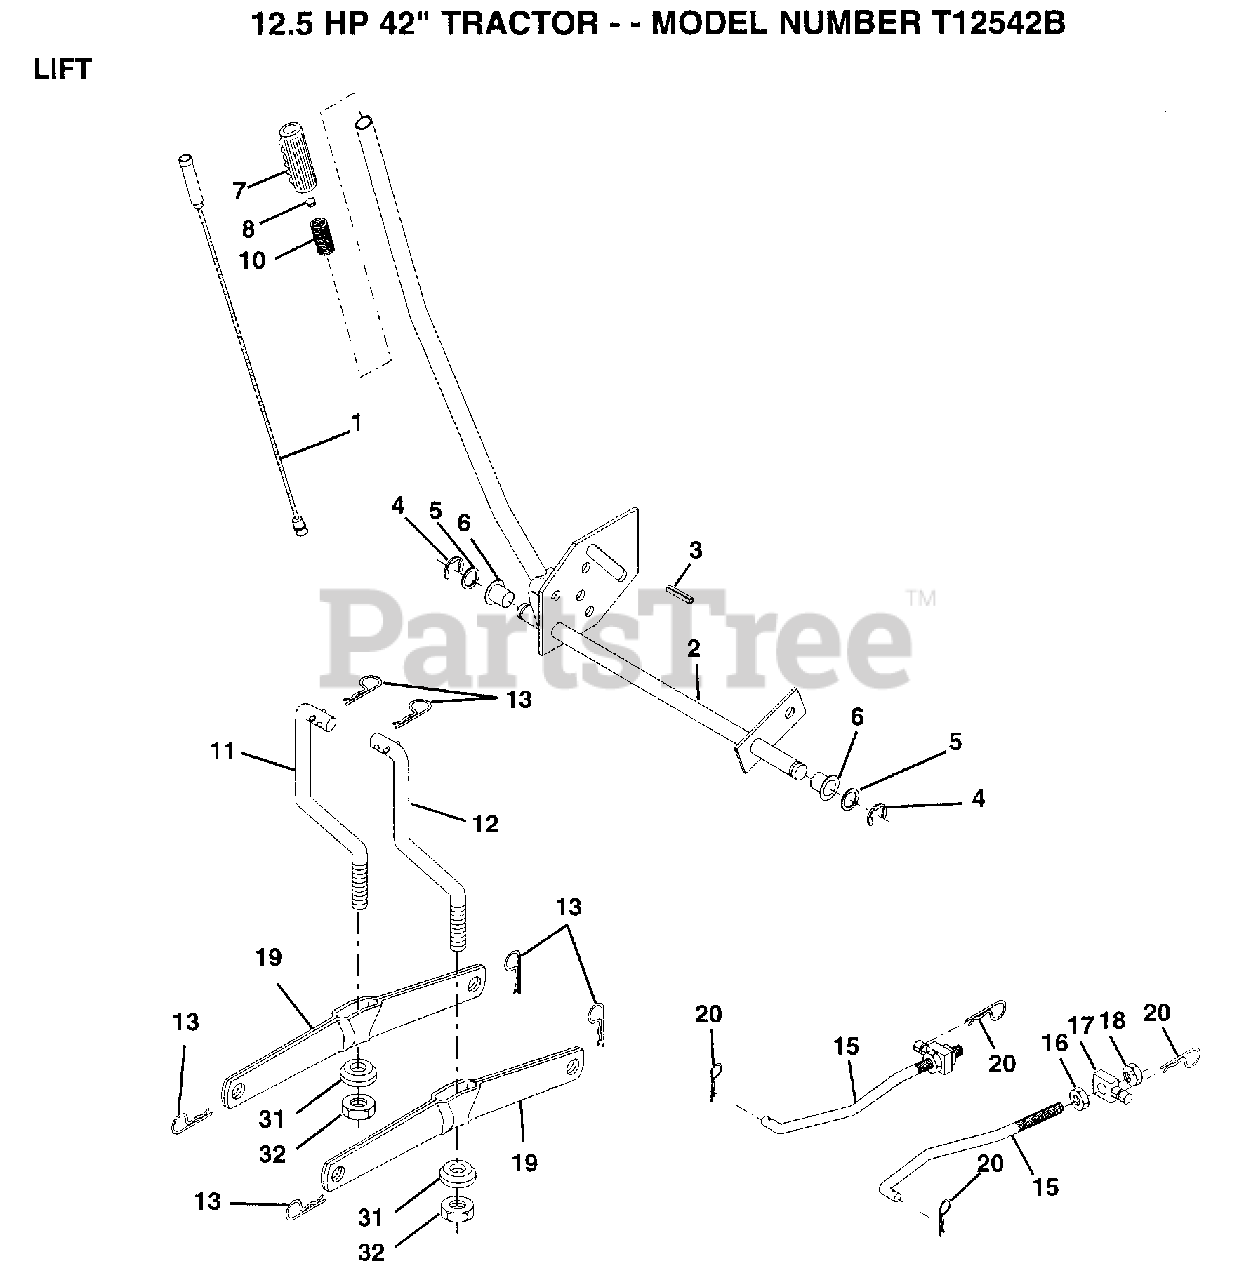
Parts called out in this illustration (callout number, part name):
1	WIRE ASM
2	HANDLE.LIFT.LH.
3	PIN GROOVE
5	WASHER
6	NYLON BEARING
7	GRIP
15	LINK.FRONT
16	NUT
17	TRUNION
18	NUT.LK.W/WSH.1/2.
19	ARM SUSP REAR
20	RETAINER.SPRING
31	BEARING PVT LH
32	NUT.LOCK.3/8-24
